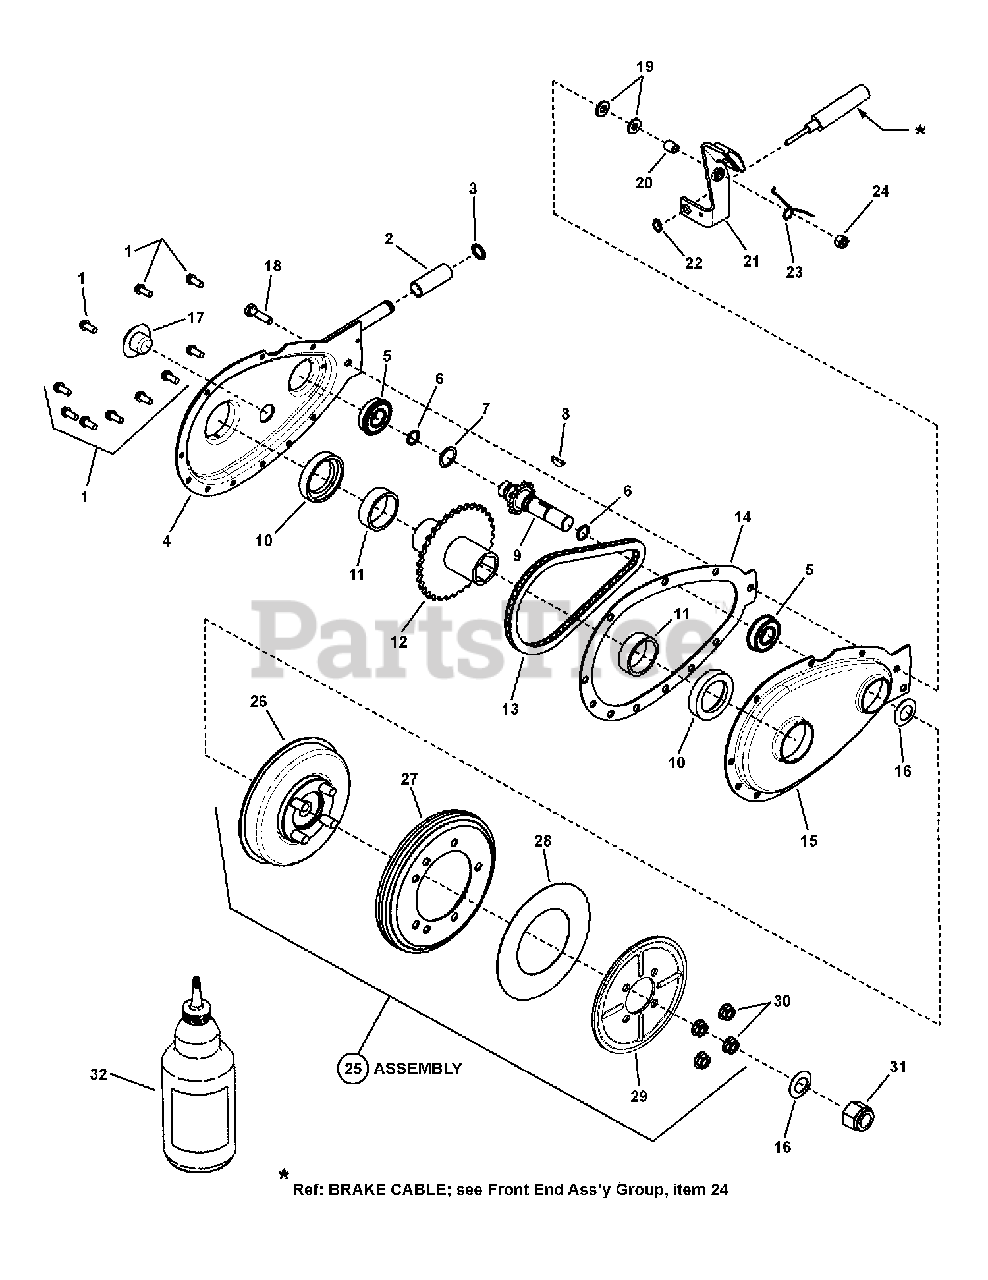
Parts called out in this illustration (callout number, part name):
1	SCREW, 10-24 x 1/2 Hex Washer Self-Tap
2	ROLLER, 1-3/8 Long
3	RING, 1/2 External Retaining (Heavy Duty)
4	WELDMENT, Primary Chain Case Half, Right Hand
5	BEARING, .625 x 1.37 x .435
6	O-RING, 1/2 x 5/8"
7	WASHER, Shim .625 x .875
8	KEY, #5 Woodruff
9	WELDMENT, Sprocket & Shaft
10	THRUST WASHER, Nylon
11	BEARING, Needle 1.355 ID x 1.6245 OD x .5 Wide
12	WELDMENT, Hub & Sprocket
13	CHAIN, 46 Pitch (#35 Endless)
14	GASKET, Primary Chain Case
15	PRIMARY CHAIN CASE HALF, Left Hand
16	WASHER, 5/8 Belleville
17	PLUG, 3/4 Cup Insert
18	SCREW, 1/4-28 x 1 Hex Head Cap, (Washer Face) GR 5
19	WASHER, Flat, 1/4
20	SPACER, Brake Arm Pivot (.418/.403 long)
21	ASSEMBLY, Brake Lever (Includes brake pad & rivet)
22	RING, 3/8 External Retaining
23	* SPRING, Torsional Brake Return
24	NUT, 1/4-28 Hex Top Lock
25	ASSEMBLY, Smooth Clutch (non-asbestos)
26	HUB, Driven Disc (assembly)
27	DISC, Driven (rubber tire bonded to rim)
28	THRUST WASHER
29	PLATE, Drive Disc
30	NUT, 5/16-24 Hex Flange Lock
31	NUT, 5/8-18 Hex Nyloc
32	** GREASE, Transmission (Use 2 oz. Maximum)
